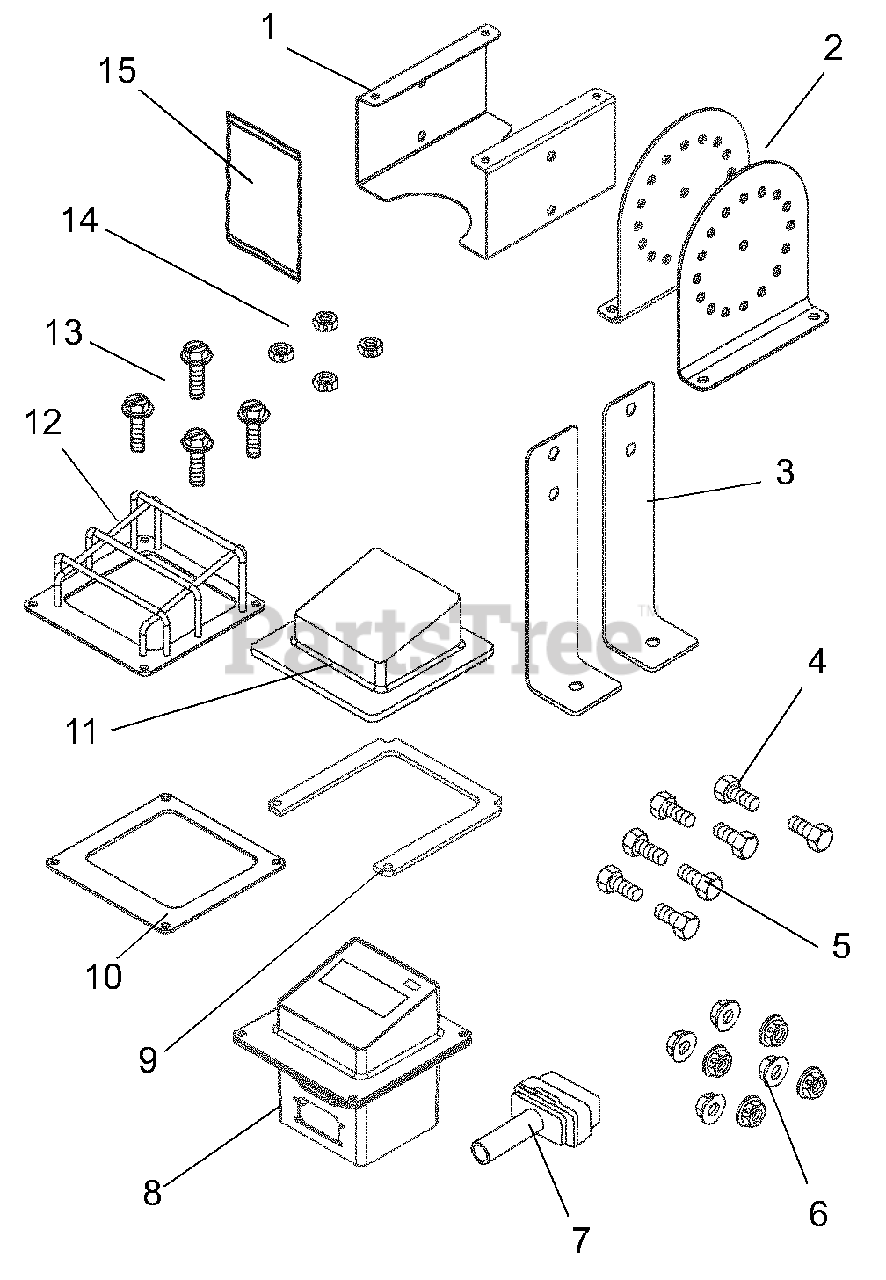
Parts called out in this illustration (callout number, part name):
1	Eye-Q(TM) Retrofit Bracket
2	Eye-Q(TM) Retrofit Leg
3	Eye-Q(TM) Retrofit Long Leg
4	1/4-20 x 1 Hex Bolt, Grade 5
5	1/4-20 x 1/2 Hex Bolt, Grade 5
6	1/4-20 Top Locking Flange Nut
7	Eye-Q(TM) Retrofit Harness
8	Eye-Q(TM)
9	Mounting Enclosure Spacer
10	Eye-Q(TM) Gasket
11	Element Guard
12	Vinyl Eye-Q(TM) G
13	10-24 x 1-1/2 Hex Washer Head Machine Screw
14	10-24 Nylon Locknut w/ Insert
15	Eye-Q(TM) Owner/Operator Manual
15	Eye-Q(TM) Owner/Operator Manual - Multilingual
